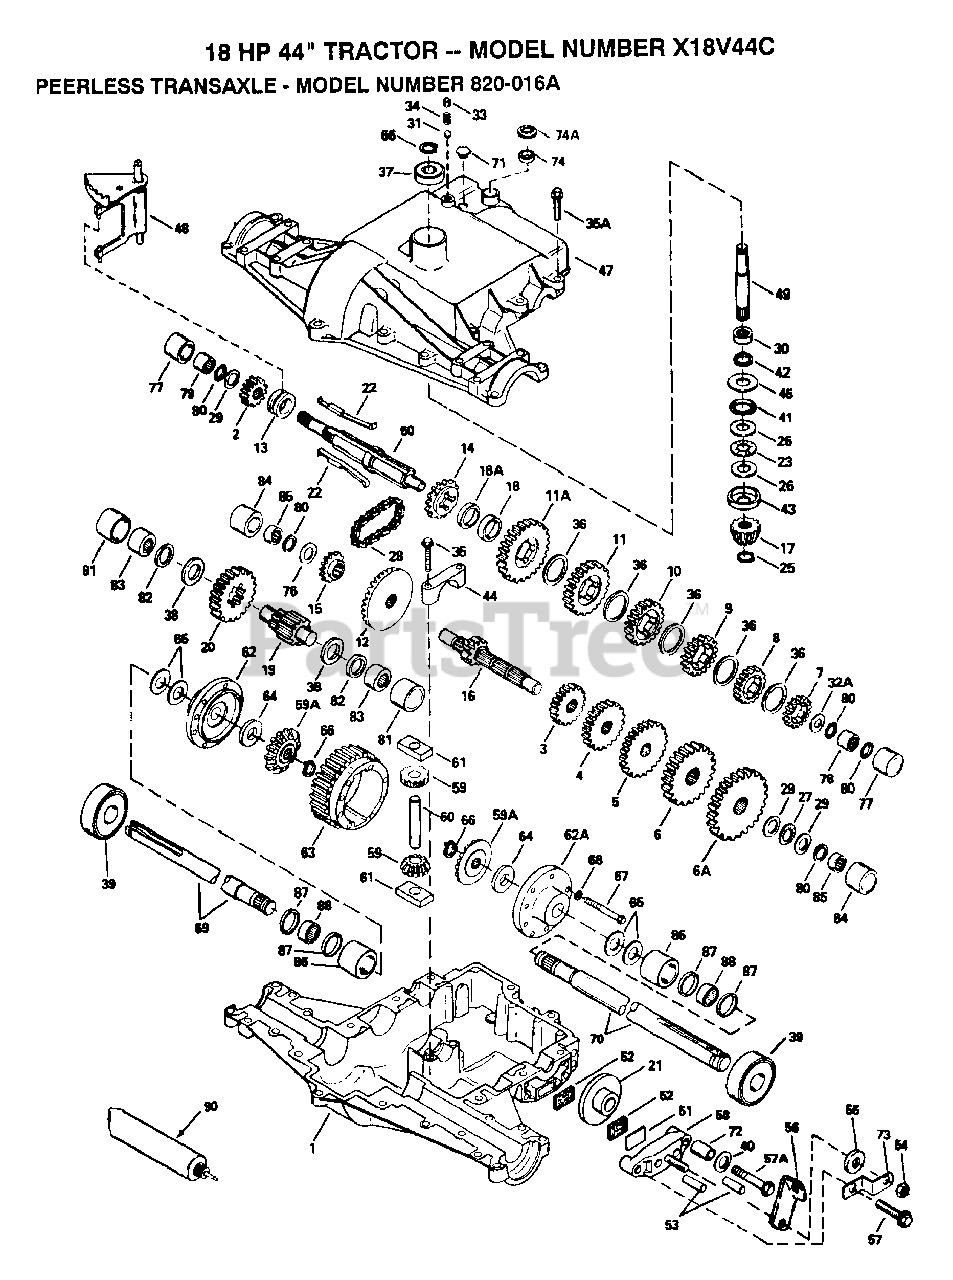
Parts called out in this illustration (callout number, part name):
1	CASE TRANSAXLE
2	GEAR, SPUR, 15T
3	GEAR, SPUR, 12 TEETH
4	GEAR, SPUR, 18 TEETH
5	GEAR, SPUR, 25T
6	GEAR, SPUR, 28T
6A	GEAR, SPUR, 31T
7	GEAR, SPUR, 19T
8	GEAR, SPUR, 22T
9	GEAR, SPUR, 25T
10	GEAR, SPUR, 32 TEETH
11	GEAR, SPUR, 37 TEETH
11A	GEAR, SPUR, 41T
12	GEAR BEVEL, 33T
13	COLLAR SHIFT
14	SPROCKET 18T (REV)
15	SPROCKET 9T
16	SHAFT COUNTER
17	BEVEL PINION, 13T
18	SPACER, .350/.340 THICK
18A	SPACER, .276/.268 THICK
19	SHAFT, OUTPUT, 9T
20	GEAR, OUTPUT, 35T
23	BEARING THRUST
25	RETAINING RING
26	WASHER THRUST
27	THRUST BEARING
28	CHAIN, ROLLER
29	WASHER THRUST
30	BEARING NEEDLE
31	BALL STEEL, 5/16" DIA.
33	SCREW, 3/8-16 X 3/8"
35	SCREW, 1/4-20 X 1-1/4
35A	SCREW HEX HD 5/16-18 X 1-1/4
36	WASHER THRUST
37	BEARING BALL
38	WASHER THRUST
39	BEARING BALL
40	WASHER FLAT
42	OIL SEAL 3/4
43	WASHER CUPPED
44	BEARING CAP
47	COVER TRANSAXLE
48	ROD AND FORK ASSY SHIFT
49	SHAFT INPUT
50	SHAFT BRAKE
51	PLATE BRAKE PAD
54	LOCKNUT 5/16-24
55	WASHER, FLAT
56	LEVER BRAKE
57	SCREW, 1/4-20 X 1-1/4
57A	SCREW FLNG HEX 1/4-20 X 2-1/4
58	HOLDER BRAKE PAD
59	PINION, 10T
61	BLOCK DRIVE
62	CARRIER DIFF THREADED HOLES
62A	CARRIER DIFF
63	GEAR, RING, 31T
65	WASHER THRUST
67	SCREW, 1/4-20 X 2-1/4
68	WASHER LOCK 1/4
69	AXLE, 12-5/16" LONG
70	AXLE, 16-3/16" LONG
71	PLUG, THRDED, 9/16-18
73	BRKT BRAKE LEVER
74	SEAL SQUARE CUT
78	BEARING NEEDLE
79	BEARING NEEDLE
81	SLEEVE STEPPED
82	RING SQ CUT
83	BEARING NEEDLE CAPPED
84	SLEEVE STEPPED
85	BEARING NEEDLE CAPPED
86	SLEEVE STEPPED
87	RING SQ CUT
88	BEARING NEEDLE
90	GREASE BENTONITE, 32 OZ.
